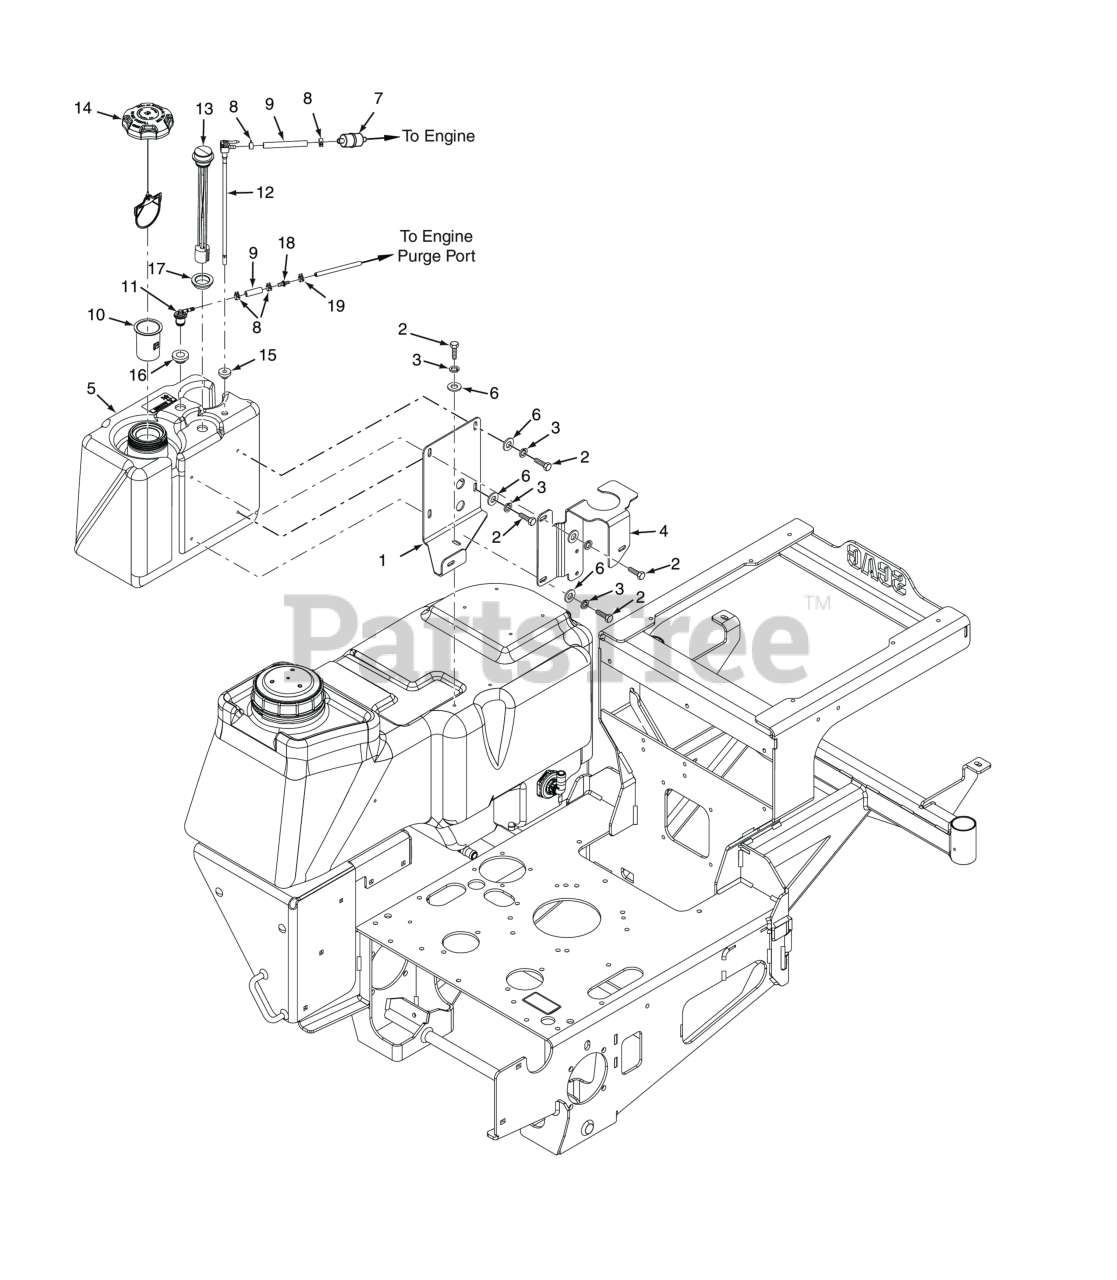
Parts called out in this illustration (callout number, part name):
1	Mounting Bracket, Fuel Tank
2	Bolt, Hex 5/16 - 18 x .75 - Stainless Steel
3	Lockwasher, 5/16 (.317 x .586 x .078) Helical Spring
4	Mounting Bracket, Oil Reservoir
5	Fuel Tank Assembly (incl. #2, 3, 5, 6, 17, 18)
6	Washer, Flat 5/16 -.375 x .875 x .0547/.104 - Stainless Steel
7	Fuel Filter
8	Clamp, Fuel Hose 1/4" Hose I.D.
9	Hose, 1/4" Vapor Recovery (order by inch)
10	TUBE, FUEL INLET - 3.00
11	Remote Vent, No Valve
12	Valve, Fuel Shutoff w/Screen
13	Fuel Gauge Assembly
14	Fuel Cap w/ Tether (E.P.A.)
15	Bushing, 0.56" Dia. Viton
16	Grommet, Viton,
17	Grommet, Fuel Gauge
18	Mender, 1/4 x 3/16 w/0.02 Hole
19	Clamp, Vapor Recovery Hose 3/16"
